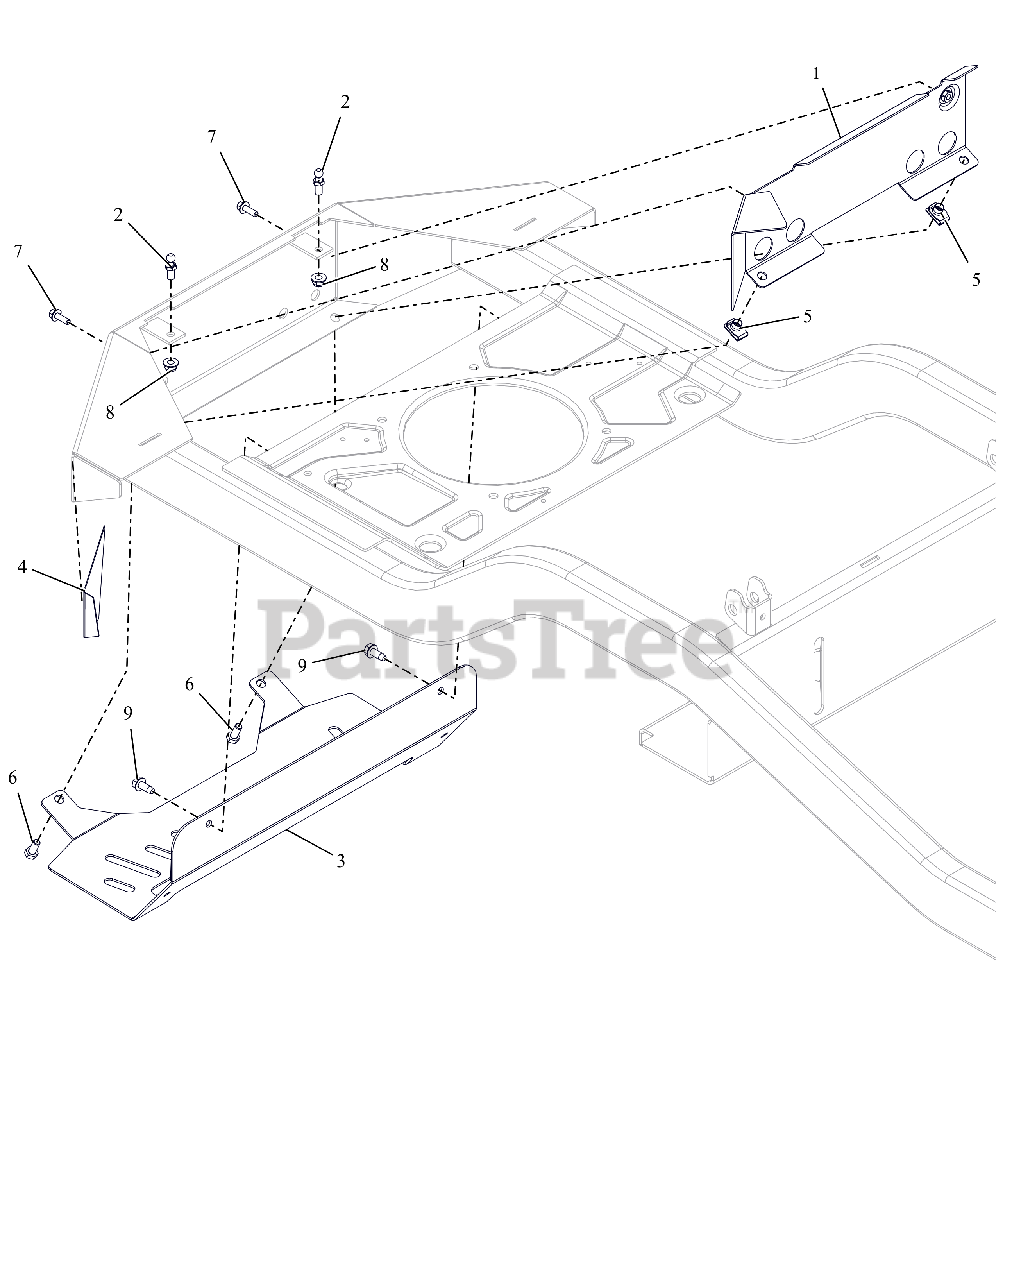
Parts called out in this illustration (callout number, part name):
1	WMT, HEAT BAFFLE
2	STUD- BALL
3	SHIELD, HEAT (HD)
4	TAPE, HEAT DEFLECTOR
5	NUT-CLIP RETAINER 5/16-18X.56
6	BLT,HEX .31-18X.75 G5 ZCC
7	BLT,HEX-FLG .25-20X.75 G5 BFP
8	NUT,LK-NYL-FLG .31-18 G5ZC120
9	SCR,TAP .312-18X.75 HWH TR ZCC
